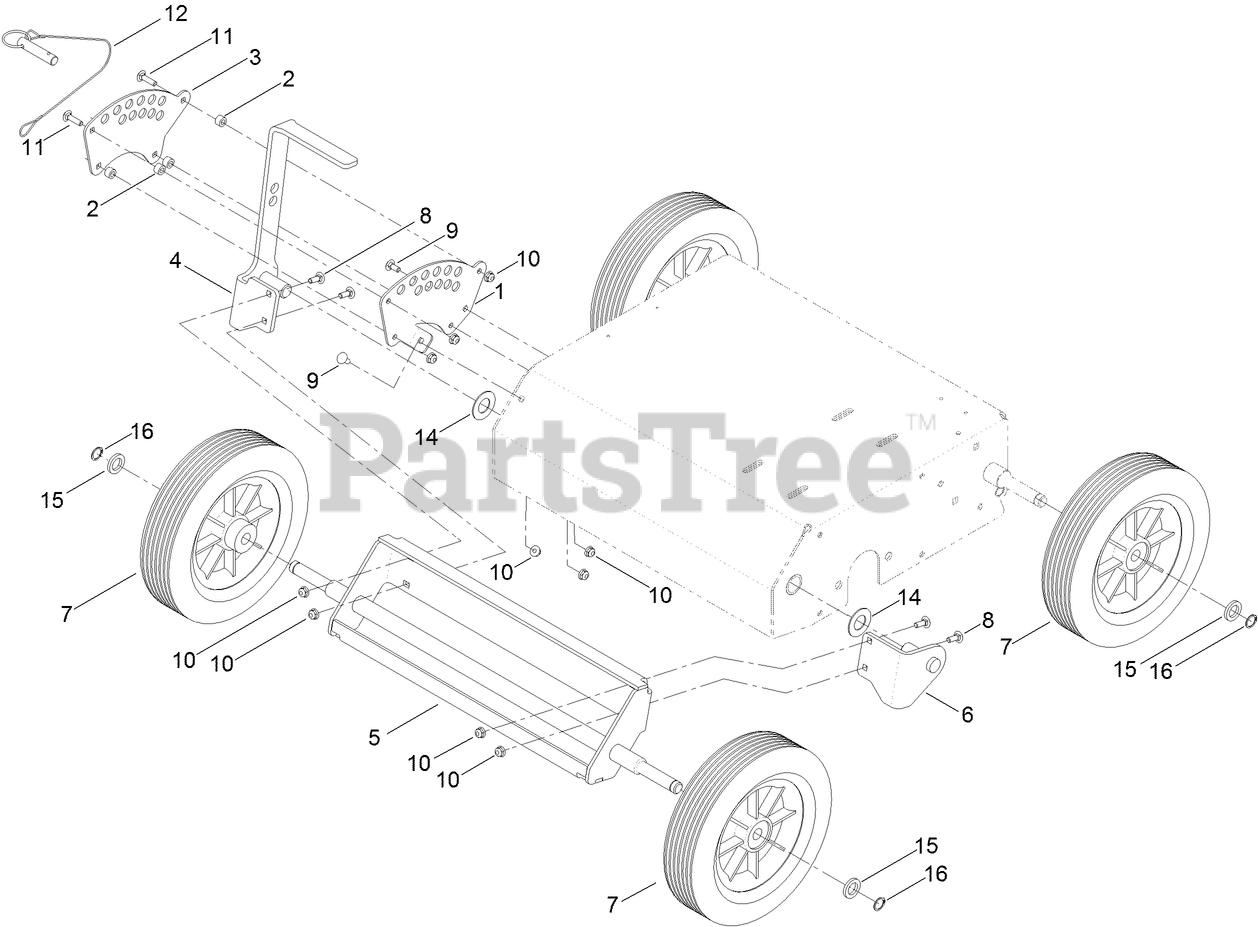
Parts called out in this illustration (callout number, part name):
1	BRACKET
2	SPACER
4	BRACKET-ADJUST, HEIGHT
5	BRACKET-WHEEL, HOC
6	BRACKET-WHEEL
7	WHEEL-10 INCH
8	BOLT-CARR
9	SCREW-CARR
10	NUT-HF
11	SCREW-CARR
12	PIN-HITCH
14	WASHER-FLAT
15	SPACER-BEARING
16	RING-SNAP, EXTERNAL
